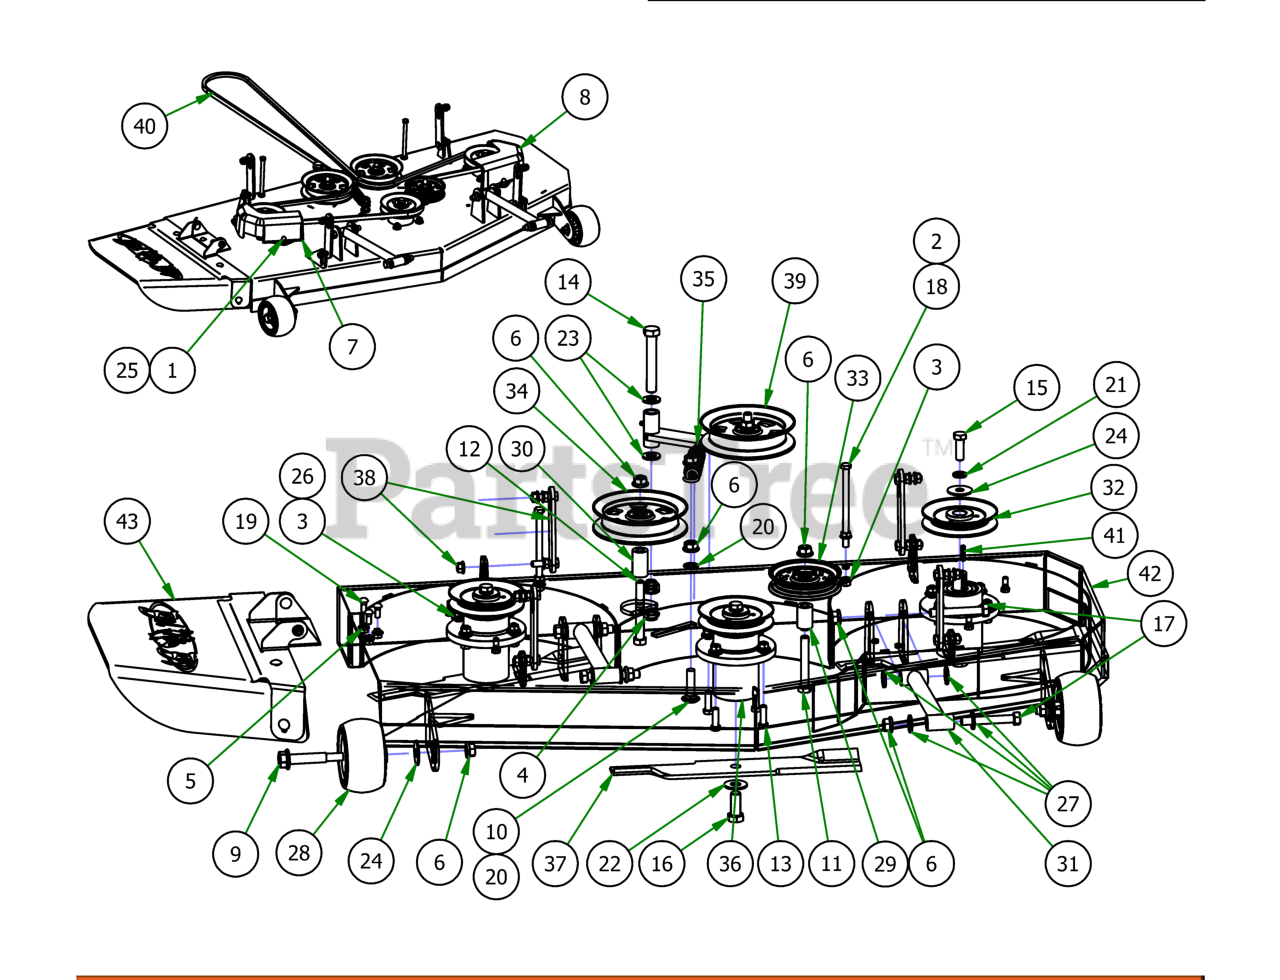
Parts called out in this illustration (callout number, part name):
1	Acorn nut-pulley Cover
2	3/8-16 HEX SERRATED FLANGE NUT HARD/ZINC
3	3/8-16 NYLON INSERT FLANGE LOCKNUT (GR.F) ZINC
4	5/8-11 NYLON INSERT JAM LOCKNUT ZINC
5	5/16-18 NYLON INSERT FLANGE LOCKNUT ZINC
6	1/2-13 NYLON INSERT FLANGE LOCKNUT ZINC
7	pulley cover chute side
8	pulley cover non-chute side
9	Deck Wheel Bolt
10	1/2 x 2" Carriage Bolt
11	1/2 x 3 1/2 Flange Bolt Grade 8
12	1/2" x 4" Bolt (Grade 8)
13	3/8" x 1 1/4" Hex Bolt
14	5/8" x 4" Hex Bolt
15	1/2"-20 x 1 1/2 - Grade 5 Fine Thread Bolt
16	5/8 x 1 1/2 Grade 8 Hex Bolt (Fine)
17	1/2-13 x 3 1/2 GR 5 Hex Bolt
18	3/8-16 x 5 1/2 Hex Bolt
19	5/16-18x3/4 carriage bolt
20	.517 Square Hole Round Washer
21	1/2" Lock Washer
22	5/8'' Flat Washer
23	.630 ID Plastic Washer
24	1/2" Belleville Washer
25	.360 ID Plastic Washer-Black
26	5/16 USS FLAT WASHER (7/8 OD) ZINC
27	.505 Nylon Spacer
28	Deck Wheel
29	.502 ID X .750 OD X 1.500 Long Spacer
30	1 3/4" Pulley Spacer
31	MZ/ZT Deck Locator
32	MZ Deck Pulley
33	4-3/4 Idler Pulley
34	5-3/4 Idler Pulley
35	Deck Idler Spring
36	Spindle Assembly-MZ
37	48" High Lift Fusion Blade
38	Deck Hanger Assembly
39	2017 54"/48" Deck Idler Assembly
40	B147 Deck Belt
41	3/16 x 1 Square Key
42	48" Welded Deck Shell
43	MZ Discharge Chute Assembly
